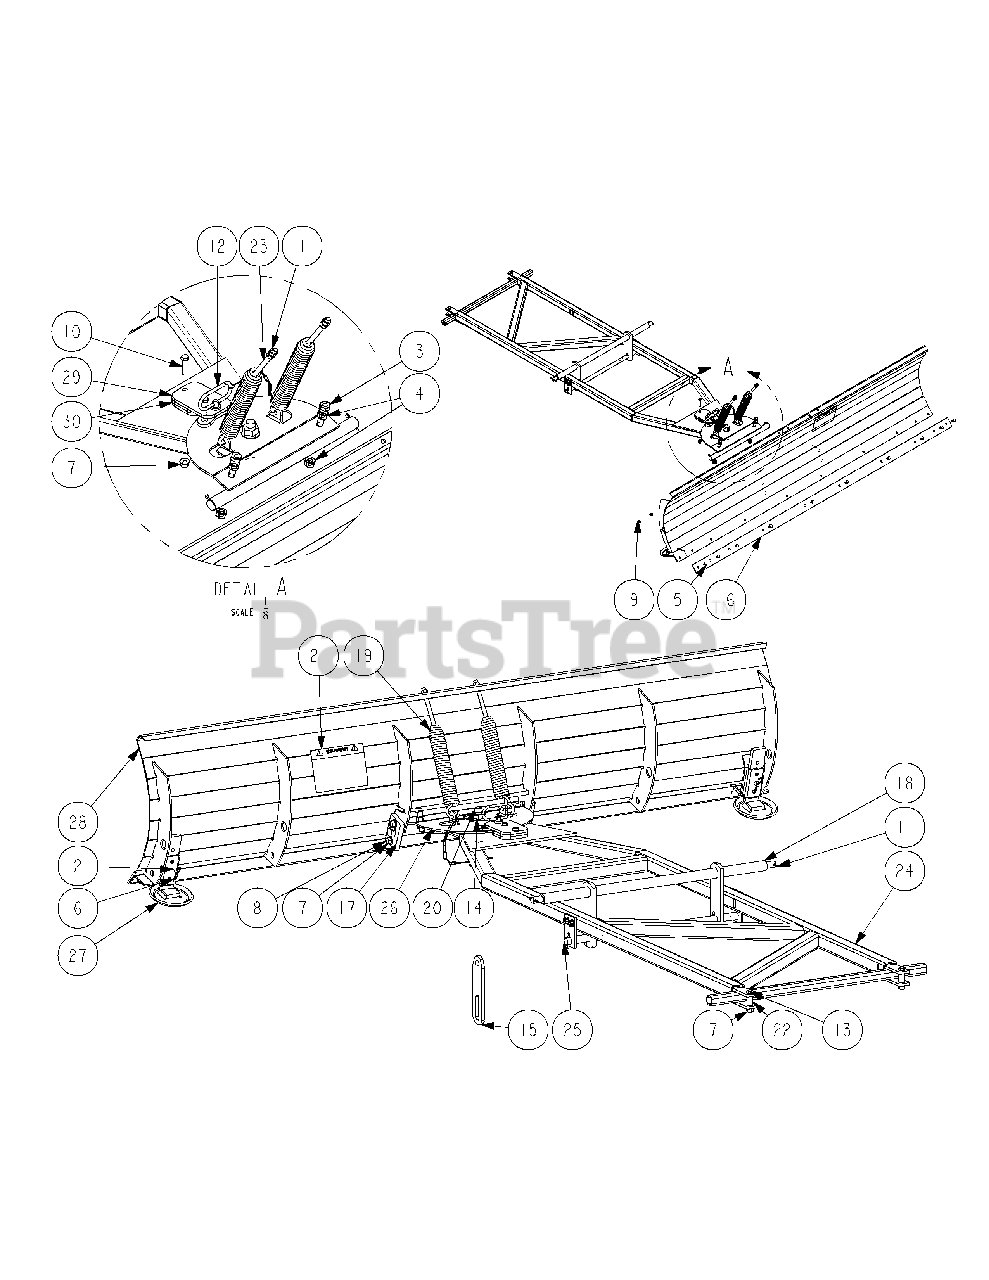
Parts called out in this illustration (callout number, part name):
1	Hex Nut 3/8-16
2	Clevis Pin, 3/8 x 1-1/8 Zinc
3	Hex Cap Screw:1/2-13 x 2.0
4	Hex Nut:1/2-13
5	Carriage Bolt:5/16-18 x .75
6	Hair Pin, 3/8-1/2
7	Flange Lock Hex Nut, 3/8-16
8	Hex Cap Screw, 3/8 -16 x 1.25
9	Hex Flange Lock Nut, 5/16-18
10	Hex Cap Screw, 3/8-16 x 1-1/2
11	Cotter Pin, 5/32, 1.25
12	Sulky Pin
13	Hex Cap Screw:3/8-16 x 2.0
14	Nut, 3/4-16, Hex Flange
15	Deck Lift Link
17	Rod Bearing Pivot Plate
20	Hex Cap Screw, 3/4-16 x 3.00
21	Label, Warning
22	Rear Support Spacer
23	Bolt:3/8-16 x 4.50
30	Plow Spacer
